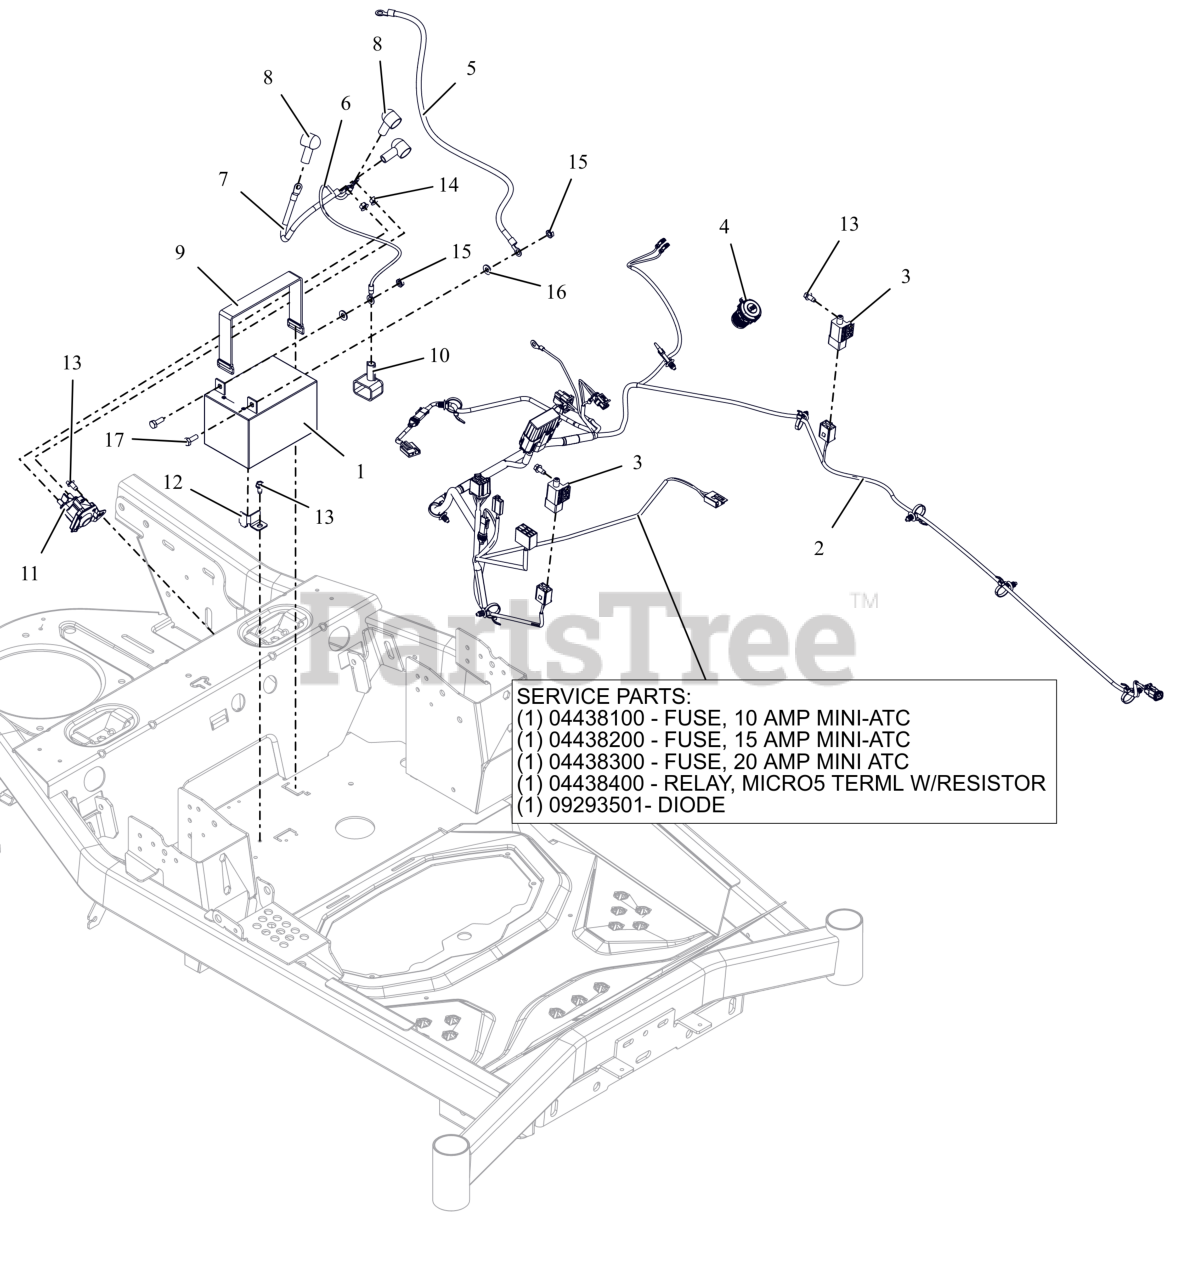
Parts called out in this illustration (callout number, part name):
1	BATTERY, 12V 12A -190CCA
2	HARNESS, MAIN IKON 23
2	FUSE,10 AMP MINI-ATC
2	FUSE,15 AMP MINI-ATC
2	FUSE,20 AMP MINI ATC
2	RELAY,MICRO5 TERML W/RESISTOR
2	DIODE, CONNECTOR SHELL
3	SWITCH-BRAKE NO/NO-POST & HOLE
4	USB, DUAL PORT USB-C, 12V BLK
5	CABLE-NEGATIVE BATTERY 24.00"
6	CABLE,POS W/2 1/4 RING 18.5 LG
7	CABLE, POS W/(2)1/4 RING 9.0LG
8	BOOT, EYELET TERMINAL
9	STRAP- RUBBER
10	INSULATOR
11	SOLENOID, STARTER (SEALED)
12	RETAINER, BATTERY CORNER (BLACK)
13	SCR-TAP .25-20X.50 HWH ZCC
14	NUT- M6-1.0 W/ CONICAL WASHER
15	NUT-KEPS .250-20 ZCC
16	WSHR,FLT .281X.625X.065 ZCC
17	BLT, HEX .25-20X.75 G5 ZCC
